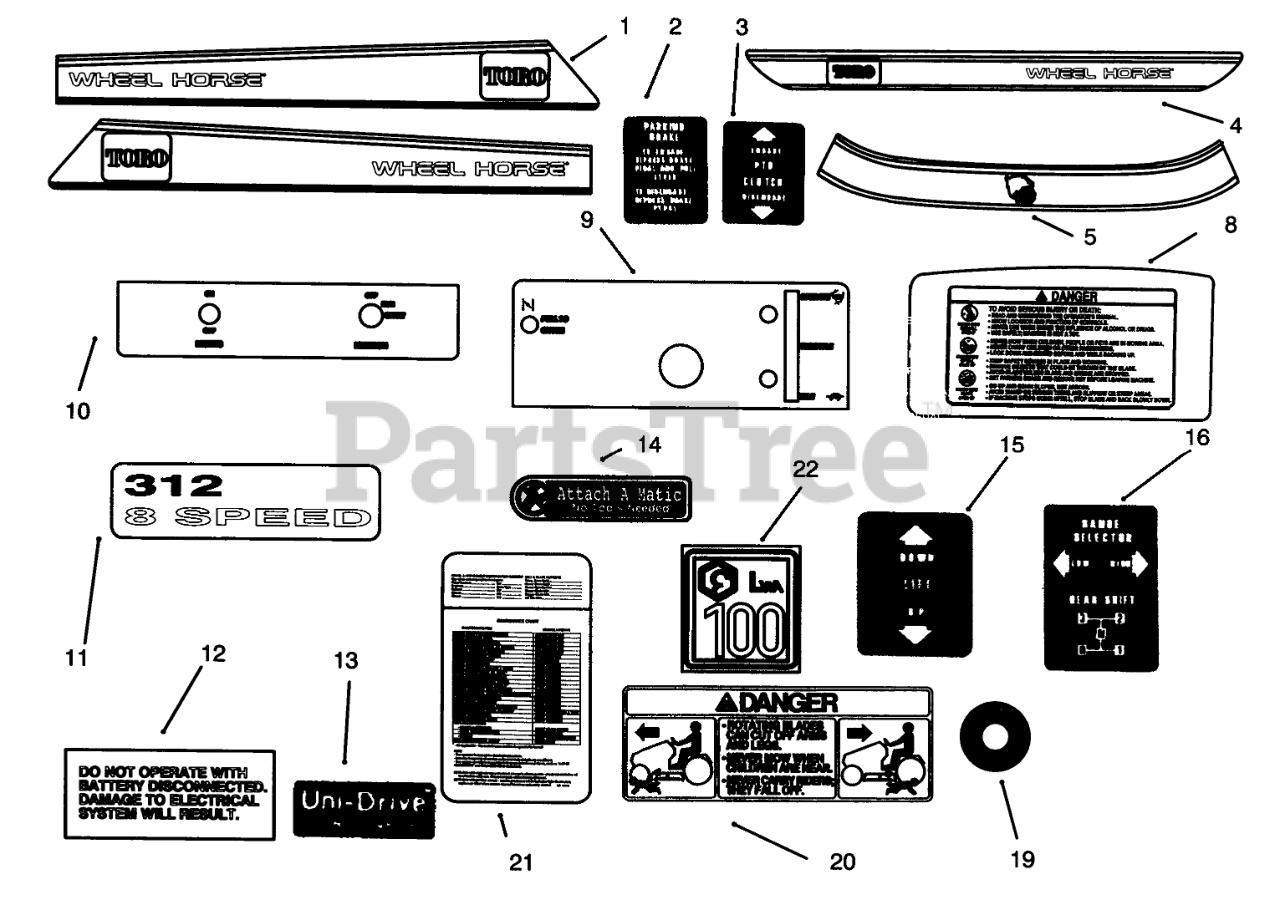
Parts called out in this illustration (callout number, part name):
1	DECAL - RH HOOD TOP
2	DECAL-PARKING, BRAKE
3	DECAL PTO CLUTCH
4	DECAL - REAR FENDER
5	DECAL-FRONT HOOD, TOP
8	DECAL - DANGER
9	DECAL-LOWER DASH
10	Decal-Black Plate
11	DECAL - MODEL 312-8
12	DECAL ELECT SYSTEM
13	Decal-Unidrive
14	DECAL-ATTACH A-MATIC
15	DECAL-LIFT
16	DECAL-SHIFT PATTERN
19	Decal-Air Cleaner
20	DECAL-DANGER
21	Decal-Maintenance
22	DECAL-EUROPE
